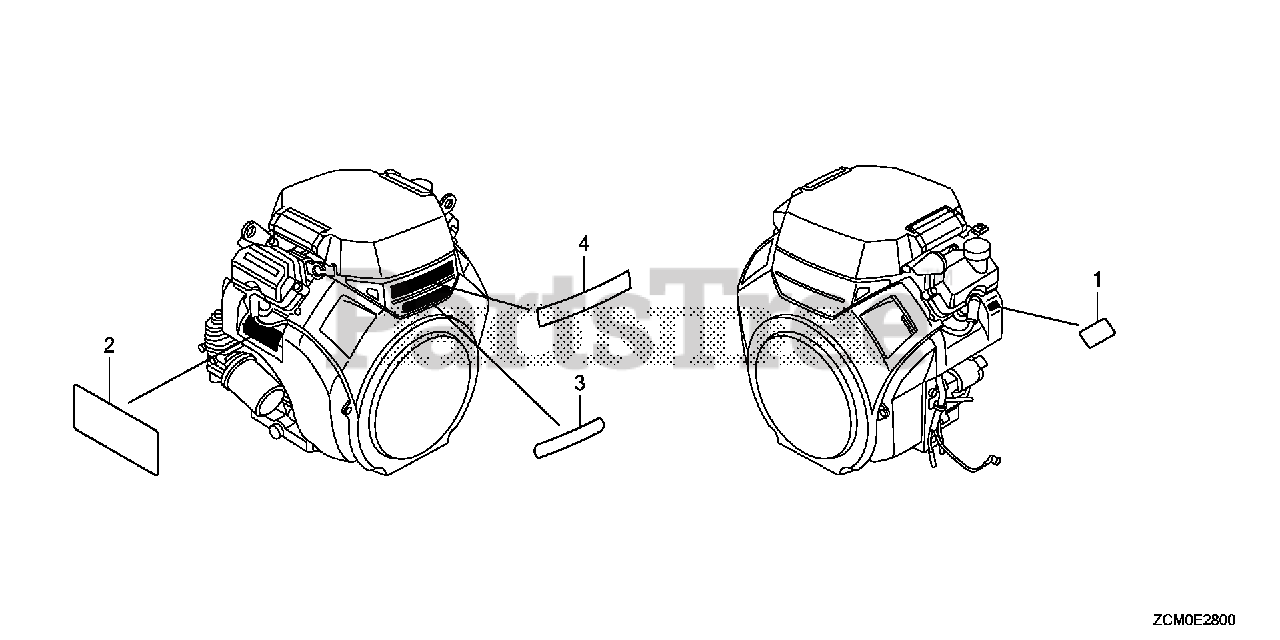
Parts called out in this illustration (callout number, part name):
1	LABEL, WARNING (NOT CERTIFIED FOR SALE)
2	MARK, OPERATOR CAUTION (GAS)(ENGLISH)
3	EMBLEM (GX690)
4	MARK, HONDA
